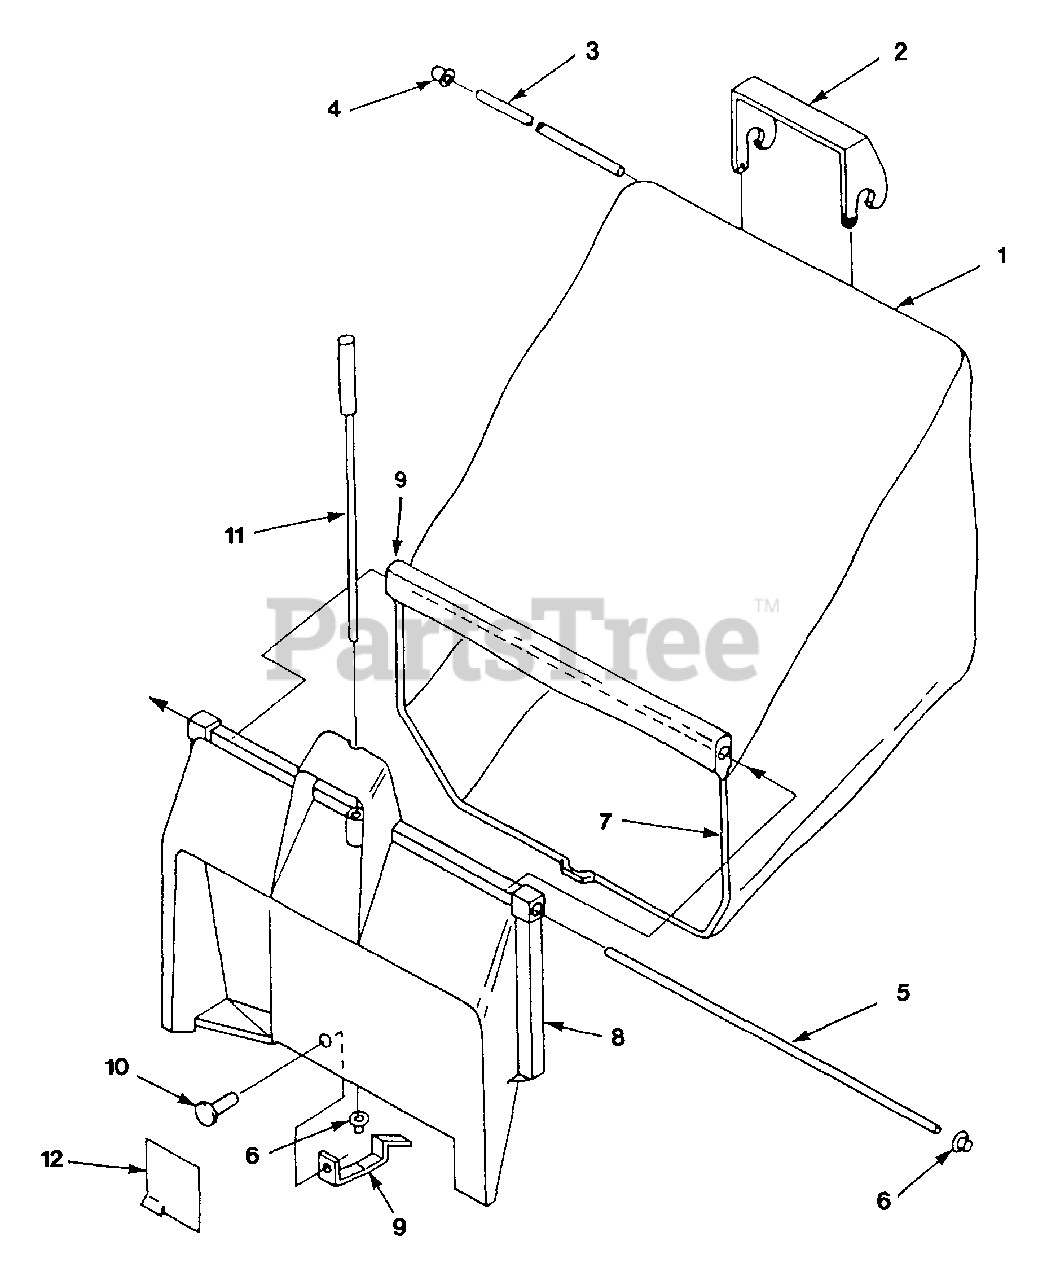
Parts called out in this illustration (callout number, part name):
1	Bag - grass catcher
2	Handle - bag
3	Rod - handle
4	Retainer - handle rod
5	Rod - bag hinge
6	Nut - Pal
7	Frame - bag, u-shaped
8	Adapter - bag
9	Latch - bag release
10	Rivet - pop
11	Rod - latch release
12	Decal - heat deflector
